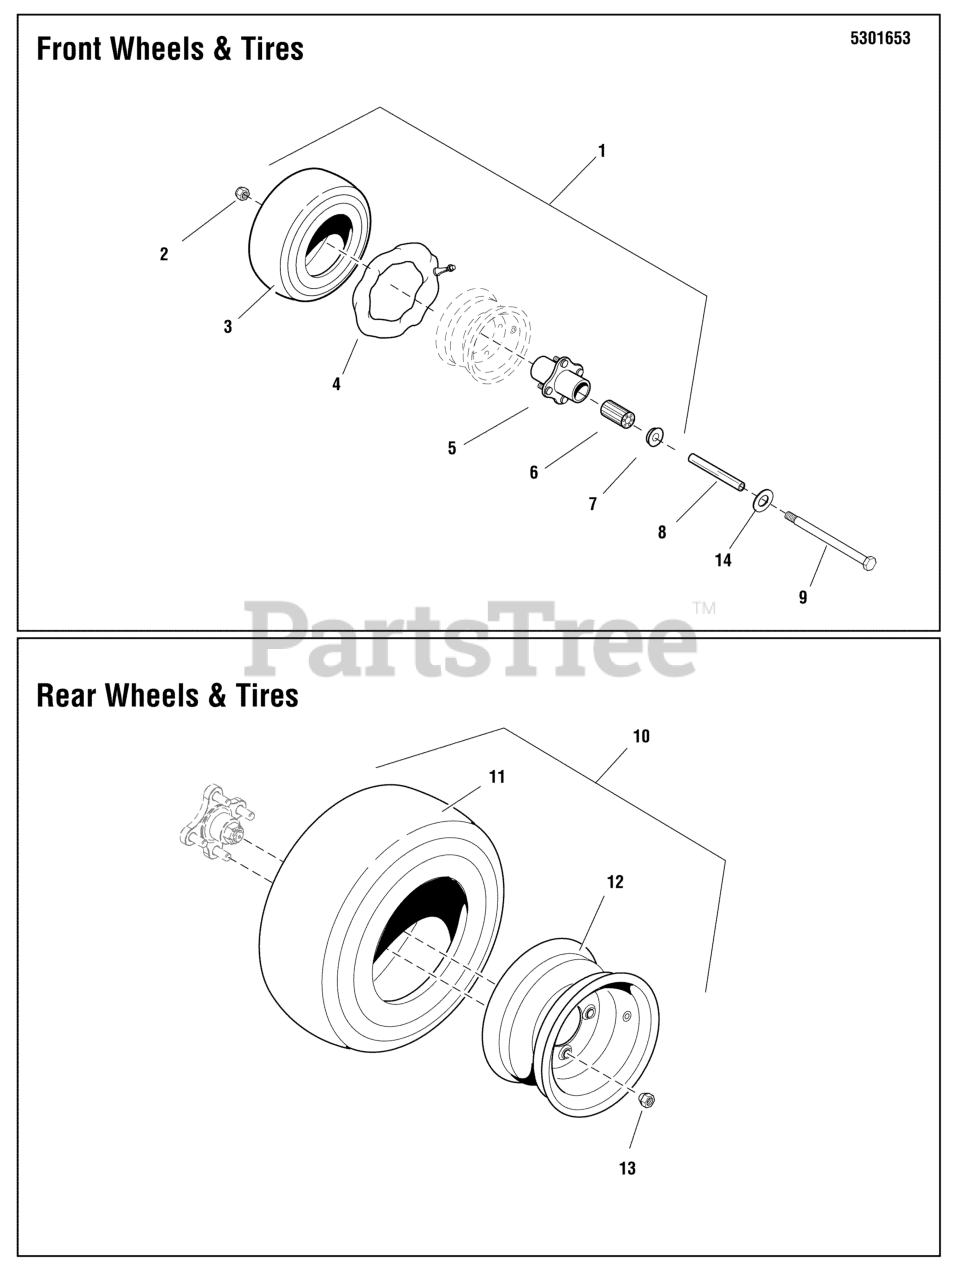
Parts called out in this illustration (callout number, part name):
1	TIRE ASSM, 9 X 3.5 X 4, SILVER
2	NUT, Hex Flange, Nylock, 1/2-13
3	TIRE, FRONT 9 X 3.5 X 4 (SV)
4	TUBE (SV)
5	HUB & BEARING ASSEMBLY (SV)
6	BEARING, ROLLER 3/4" ID X 3.25" (ONE PER TIRE)(SV)
7	RETAINER, BEARING (TWO PER TIRE)(SV)
8	AXLE, CASTER WHEEL
9	BOLT, 1/2-13 X 5-1/2" GD5 YZ
10	TIRE, 18 X 8.5 X 8, 4 PLY
11	TIRE ONLY (SV)
12	WHEEL ONLY (SV)
13	NUT, 1/2-20, FOR WHEEL BOLT SILVER
14	WASHER, 1/2 SAE
